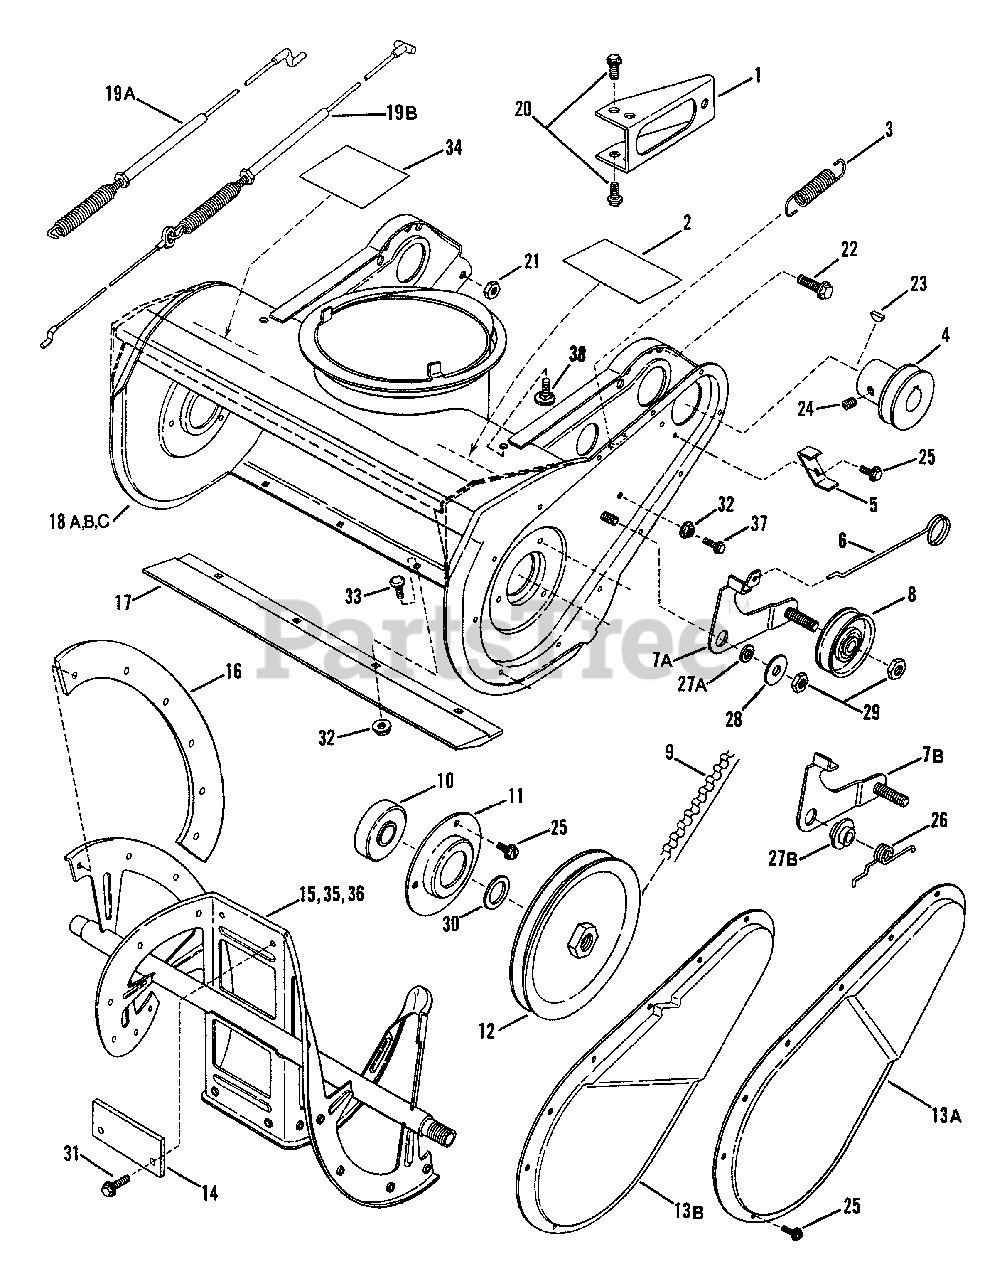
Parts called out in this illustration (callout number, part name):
1	BRACE, Engine
2	DECAL, Collector
3	SPRING, Brake
4	PULLEY, Engine
5	GUIDE, Belt
6	LINKAGE, Idler
7A	ASSEMBLY, Idler Arm
7B	ASSEMBLY, Idler Arm
8	PULLEY, Idler Arm
9	BELT, Auger
10	BEARING, Auger
11	RETAINER, Bearing
12	PULLEY
13A	COVER, Belt
13B	COVER, Belt
14	FLIGHTING SHOE
15	AUGER
16	FLIGHTING SHOE
17	BLADE, Scraper
18A	ASSEMBLY, Blower
18B	ASSEMBLY, Blower
18C	ASSEMBLY, Blower
19A	CABLE, Clutch
19B	CABLE, Clutch
20	SCREW, 1/4-20 x 3/8" Hex Washer Head Self-Tap
21	NUT, 1/4-20 Hex Center Lock, Grade B or 5
22	BOLT, 5/16-18 x 5/8" Hex Head Flange Lock
23	KEY, (#6) 5/32 x 5/8" Woodruff
24	SET SCREW, 1/4-20 x 5/16" Cup Point Socket Head
25	SCREW, #10-32 x 1/4" Hex Washer face Self-Tap
26	SPRING, Idler Brake
27A	SPACER, Bearing
27B	SPACER, Bearing
28	WASHER, 5/16 SAE
29	NUT, 5/16-18 Hex Center Lock
30	WASHER, .767 I.D., 1.125 O.D. Flat
31	SCREW, #10-24 x 5/8" Hex Washer Self-Tap
32	NUT, #10-24 Hex Flange Lock
33	BOLT, #10-24 x 1/2" Square Neck Carriage, Grade 2
34	DECAL, Instruction
35	KIT, Rubber Blade Replacement
36	ASSEMBLY, Auger
37	SCREW, #10-24 x 5/8" Hex Washer Face Self-Tap
38	BOLT, #10-24 x 1/2" Flat Head Carriage
